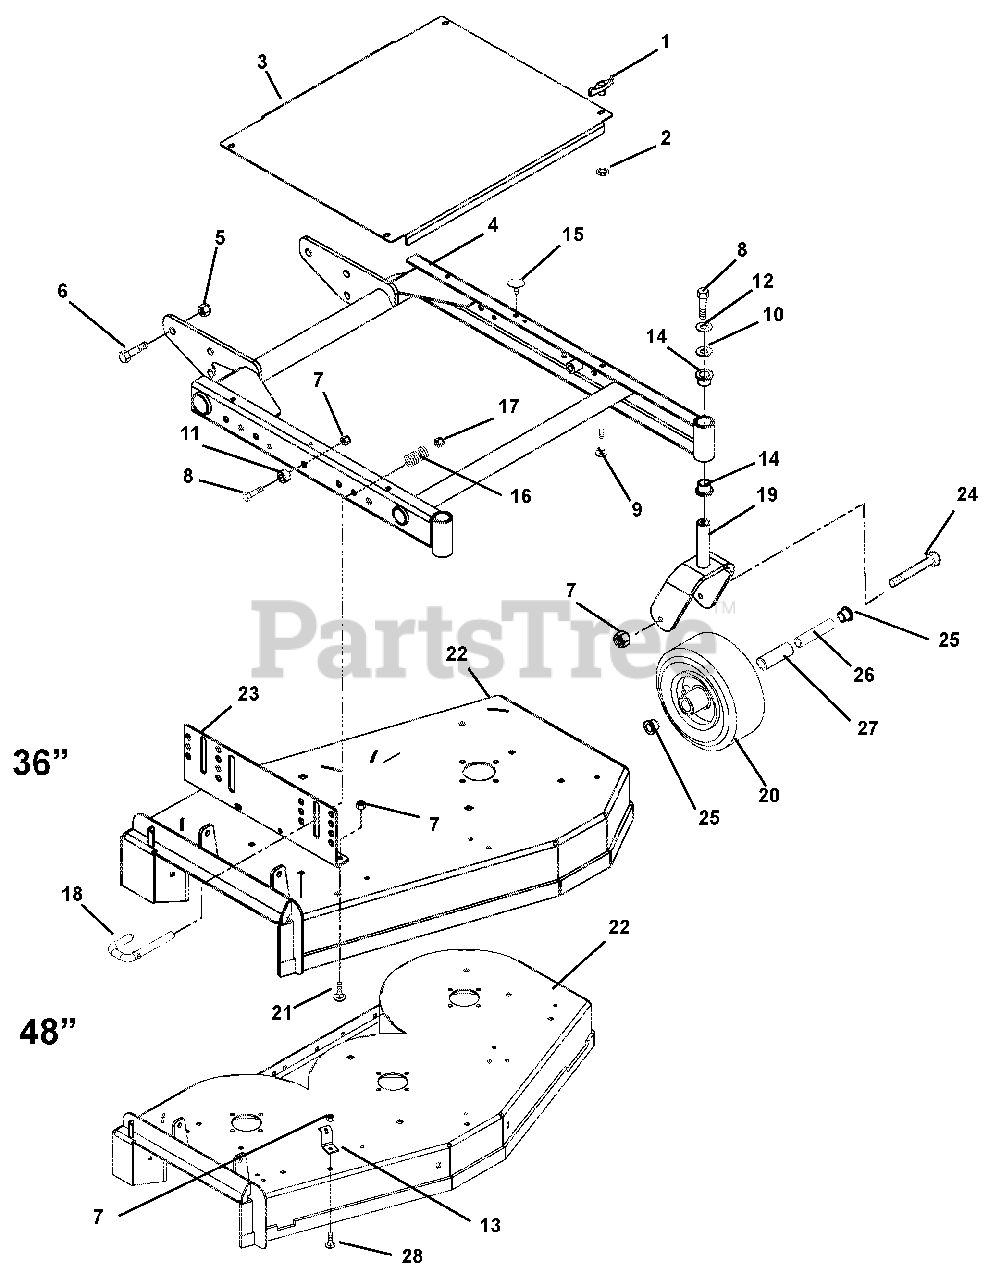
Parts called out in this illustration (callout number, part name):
1	Knob- Wing .312-18 (105, 106, 120)
2	Nut-Push .312 (105, 106, 120)
3	Cover, Belt Pro Mower (105, 120)
4	Weldment - Mower Frame 36" (105, 120)
5	Nut-Locking-Nylon .625-11
6	Bolt-Hex .62-11 x 1.50
7	Nut-Locking-Top-Flange .38-16 (105, 120)
8	Bolt-Hex .38-16 x 1.25 Grade 5
9	Bolt-Round Head Square Neck .31-18 x 1.00 (105, 106, 120)
10	Washer-Flat-Steel .38 x 1.50 x .125
11	Bushing
12	Washer-Locking .38 x .094 Regular
13	Anchor, Spring (106)
14	Bushing-Flange 1.00 x 1.25 x 1.50 x 1.50
15	Bumper Grommet .125 x .25 Dia.
16	Spring-Compression .058 x .65 x 2.13
17	Nut-Locking-Center .50-13
18	Pin- Latch
19	Weldment-Caster Fork
20	Wheel 9 x 3.50
21	Bolt-Round Head Square Neck .38-16 x 1.00 Grade 5 (106, 120)
22	Kit, 36" Fixed Mower Deck with Decals (105, 120)
23	Kit-Mower Side Support Bracket-Right Hand and Left Hand
24	Bolt-Hex .38-16 x 5.50
25	Bearing-Retainer
26	Bearing .625 x .380 x 4.08
27	Bearing-Roller
28	Bolt-Round Head Square Neck .38-16 x .75 Grade 5
